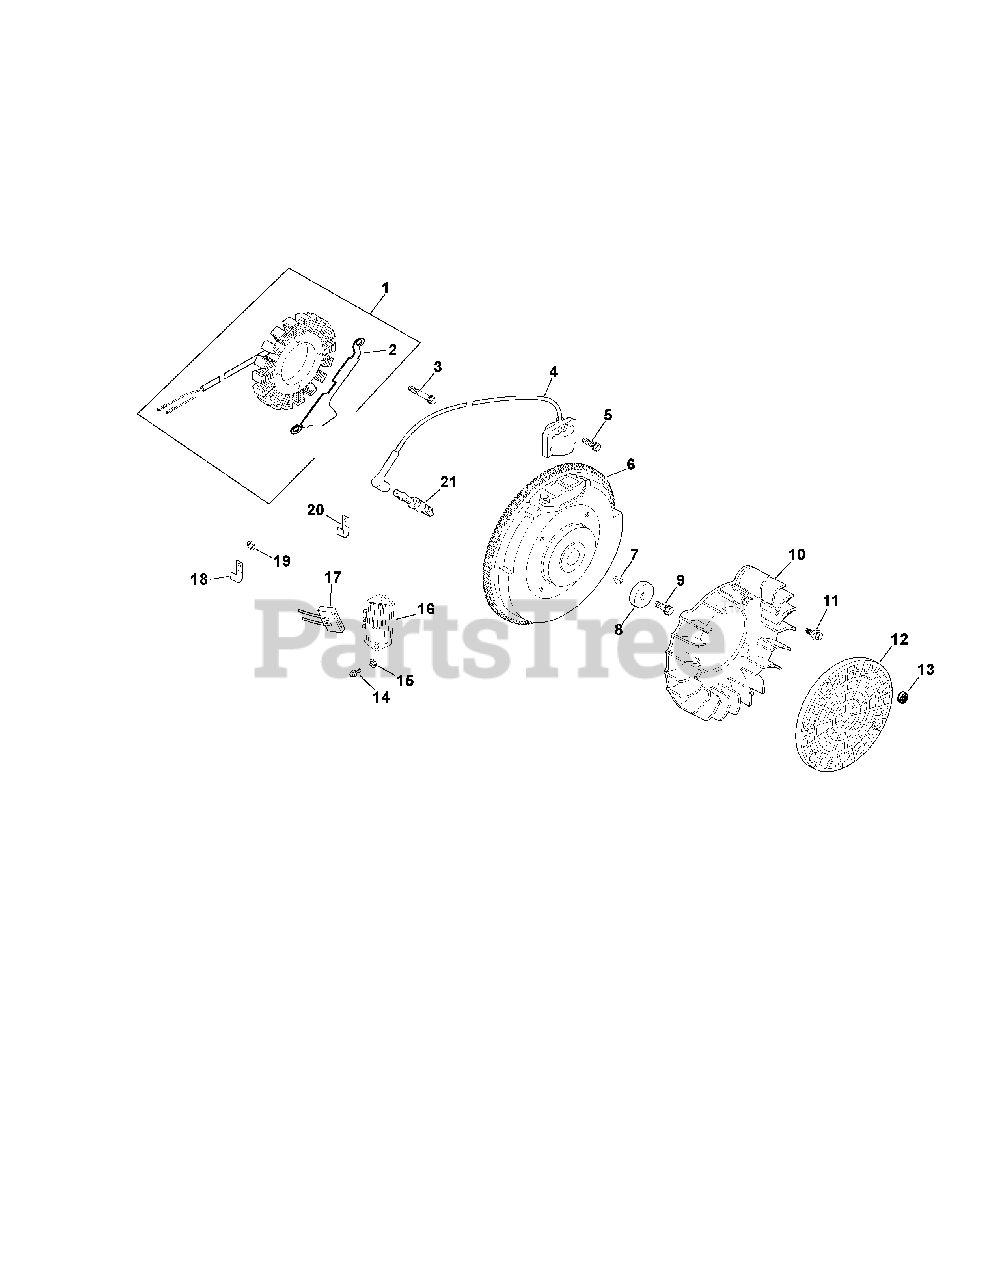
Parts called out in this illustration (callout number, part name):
1	Kit, 15 amp stator (Includes 2)
2	Bracket, stator wire
3	Screw, hex. cap M5x0.8x25 (2)
4	Module, ignition (2)
5	Screw, hex. flange M5x0.8x20 (4)
6	Flywheel
8	Washer, plain 3/8"
9	Screw, hex. flange M10x1.5x46
10	Fan
11	Bolt, shoulder (4)
12	Screen, grass
13	Retainer, grass screen (3)
14	Screw, phillips hd. 11-16x7/8" (2)
15	Washer, plain 3/16" (2)
16	Rectifier-regulator 15 amp
17	Connector (3 contact)
18	Clip, cable
19	Washer, plain 1/4"
21	Spark Plug
